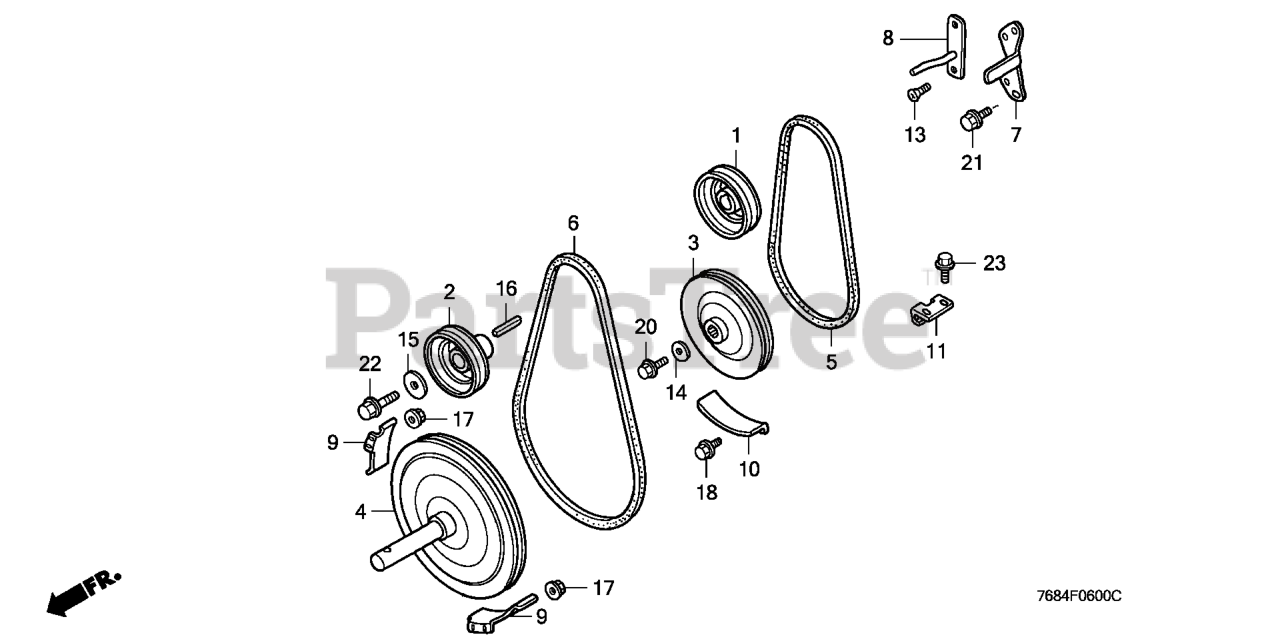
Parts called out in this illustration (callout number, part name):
1	PULLEY, WHEEL DRIVEN
2	PULLEY, AUGER DRIVE
3	PULLEY, WHEEL DRIVEN (133MM)
4	PULLEY, AUGER DRIVEN (198MM)
5	V-BELT (SA-29)
6	V-BELT (SB-35)
7	STOPPER, R. BELT (L. SIDE)
8	STOPPER, L. BELT (R. SIDE)
9	STOPPER, AUGER BELT
10	PROTECTOR, BELT (WHEEL)
11	GUIDE, BELT
13	BOLT, DOOR LOCK STRIKER
14	WASHER, CAMSHAFT SIDE
15	WASHER, LOCK (8MM)
16	KEY (7X7X33)
17	NUT, FLANGE (6MM)
18	BOLT, FLANGE (6X12) Use up to Engine SN 1543277.
20	BOLT, FLANGE (6X16)
21	BOLT, FLANGE (8X16) Use from Engine SN 1000016.
22	BOLT, FLANGE (8X28)
23	BOLT, FLANGE (6X12) Use up to Engine SN 1543277.
